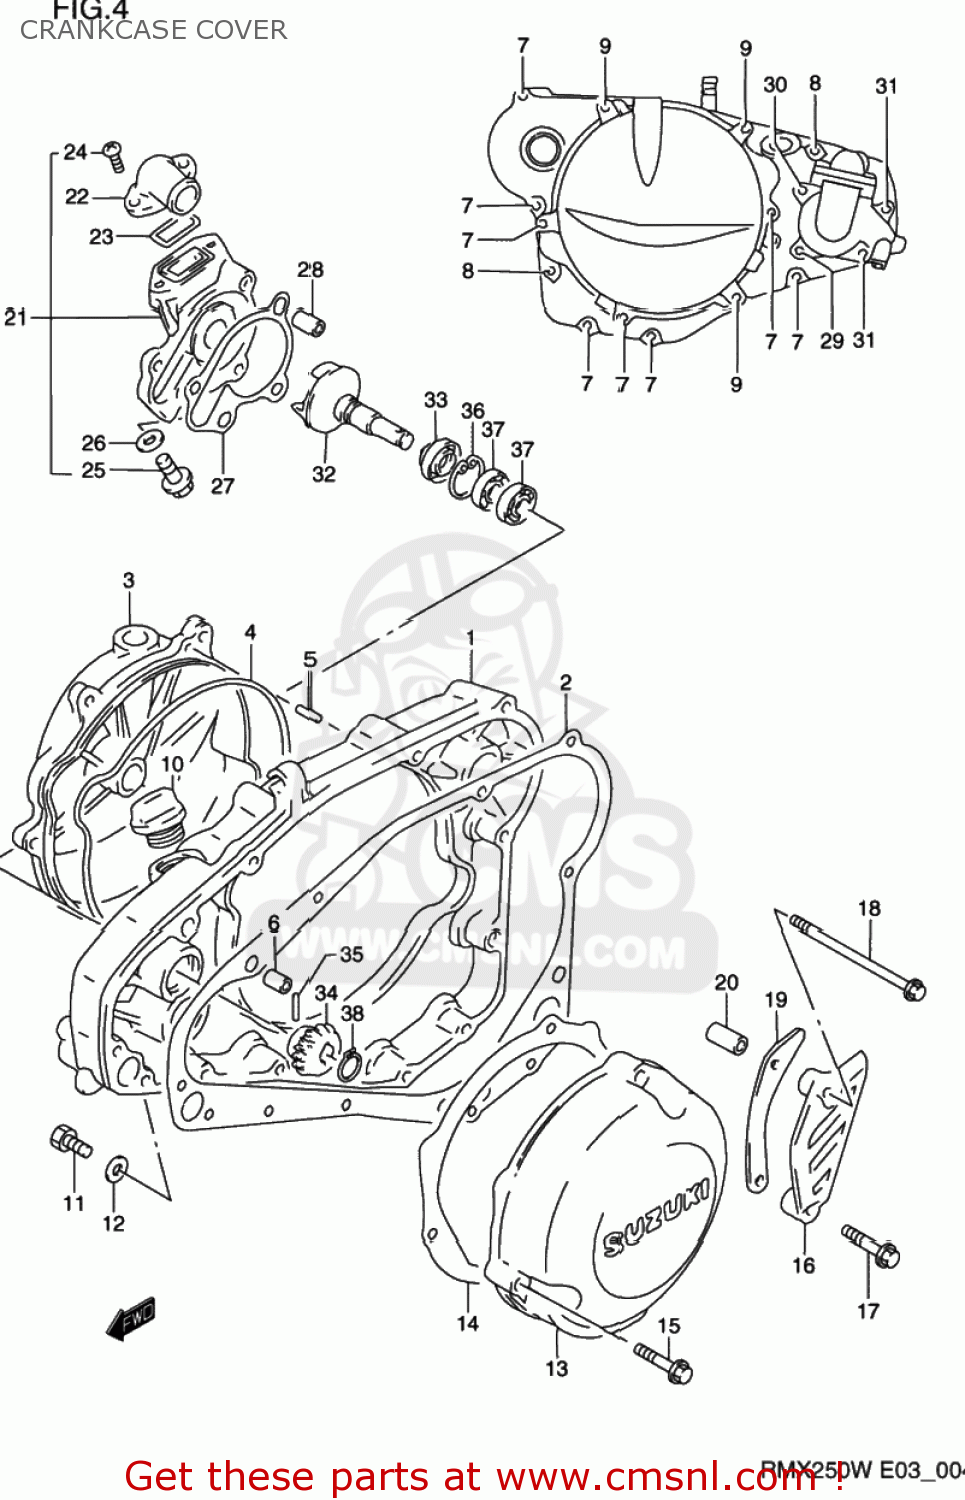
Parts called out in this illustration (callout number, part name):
1	COVER,CLUTCH
2	GASKET,CLUTCH COVER (NAS)
3	COVER,CLUTCH OUTER
4	O RING,CLUTCH COVER OUTER
5	PIN
6	PIN
7	SCREW
8	BOLT
9	BOLT
10	PLUG SET
11	SCREW(6X10)
12	GASKET(6.2X11X1).2 (NAS)
13	COVER,MAGNETO
14	GASKET,MAGNETO COVER (NAS)
15	SCREW
16	COVER,ENGINE SPROCKET
17	SCREW
18	BOLT
19	PLATE,FR CHAIN GUIDE(13T)
20	SPACER(6.5X10.5X25)
21	CASE ASSY,WATER PUMP
22	CONNECTOR
23	O RING,WATER PUMP CONNECTOR
24	SCREW
25	BOLT
26	WASHER
27	GASKET,WATER PUMP CASE (NAS)
28	PIN
29	SCREW
30	BOLT,G/S SWITC
31	BOLT
32	IMPELLER,WATER PUMP
33	SEAL,WATER PUMP OIL
34	GEAR,WATER PUMP DRIVEN(NT:24)
35	PIN(3X13.8)
36	CIRCLIP
37	BEARING
38	CIRCLIP,10MM
